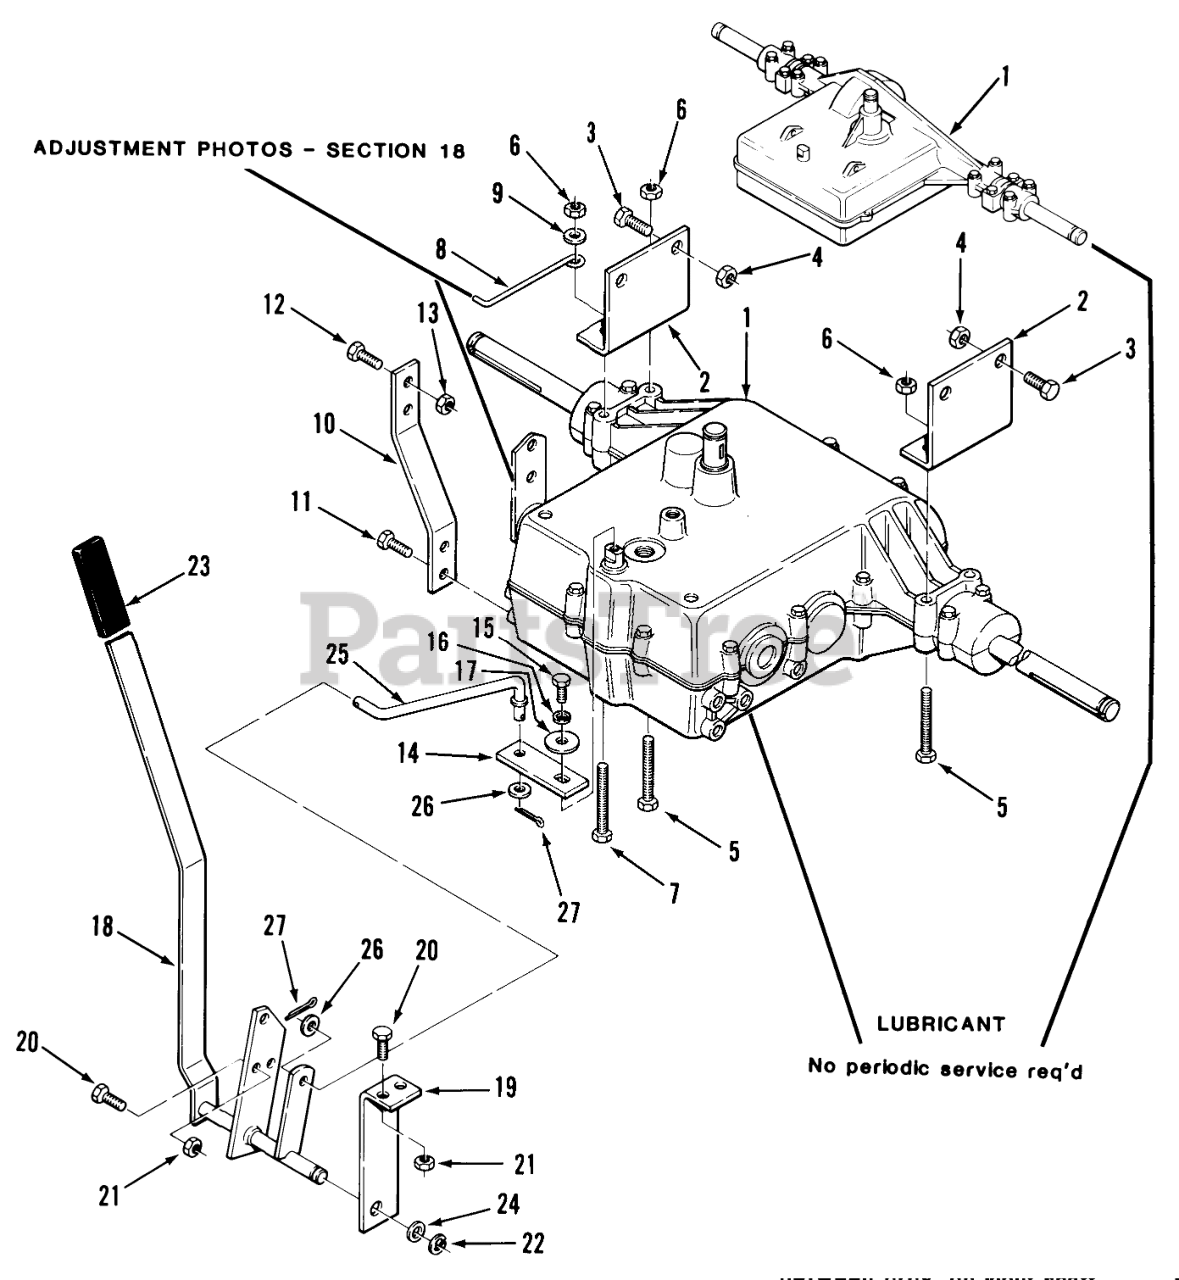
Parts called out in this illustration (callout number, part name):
1	Peerless Transmission (900-012A) 108-3 Only
1	Peerless Transmission (829-A) 108-5, 111-5 Only
2	Bracket-Rear Axle
3	BOLR HWH 3/8-16X7/8
4	NUT
5	HHCS
6	Nut
7	Pin-Cotter
8	STOP BRAKE
9	WASHER 5/16 SAE
10	STRAP TORQUE
11	Screw
12	Bolt
13	Nut
14	LEVER LOWER SHIFT
15	Bolt 1/4-28 X 7/8
16	Washer
17	WASHER
18	ASSY LEVER SHIFT R
19	SUPPORT SHIFT
20	Bolt
21	Nut
22	E Ring
24	Washer
25	ROD SHIFT LOWER
26	WASHER 5/16 SAE
27	Cotter Pin
